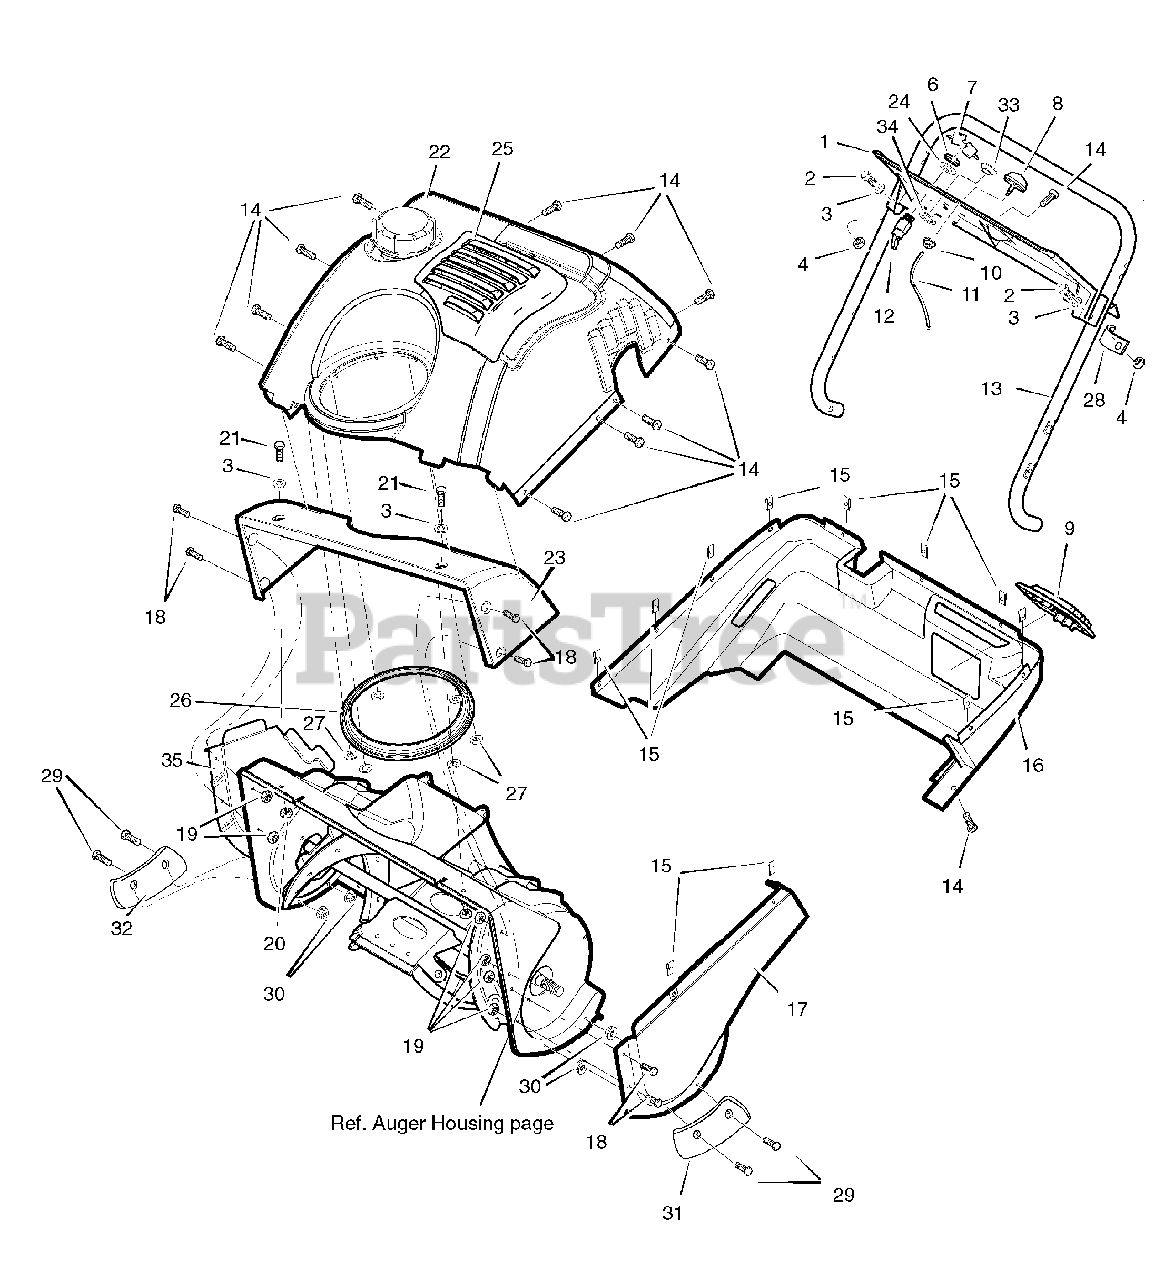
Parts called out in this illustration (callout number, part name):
1	PANEL, Control 22" SS DLR
2	SCREW, 1/4-20 x 1.25
3	WASHER, Flat 9/32 x 5/8 x .065
4	NUT, 1/4-20
6	NUT, 5/8-32
7	KEYS & RING, Starter
8	BULB, Fuel Primer
9	PANEL, Access 22" SS DLR
10	NUT, Keps 1/4-20
11	HOSE, Primer 9.5"
12	SWITCH, Ignition
13	HANDLE, Lower
14	SCREW 1/4-14 x 3/4
15	J-NUT 1/4-10
16	COVER, Bottom 22" SS DLR
17	COVER, Belt 22" SS DLR
18	SCREW 10-24 x 1/2
19	LOCKNUT, Hex 10-24 Regular Center Lock
20	LOCKNUT, Hex 1/4-20
21	SCREW 1/4-20 x 5/8
22	COVER, Top 22" SS DLR
23	COVER, Auger Top 22" SS DLR
24	WASHER, Interlock 41/64 x 1.1
25	COVER, Access Oil
26	GASKET, Chute Ring
27	NUT, Push
28	CLIP, Cable
29	SCREW 10-32 x 3/4
30	NUT 10-32 Nylock
31	SHOE, Skid L.H.
32	SHOE, Skid R.H.
33	ROPE GROMMET
34	ROPE GROMMET, Washer
35	COVER, Auger R.H.
